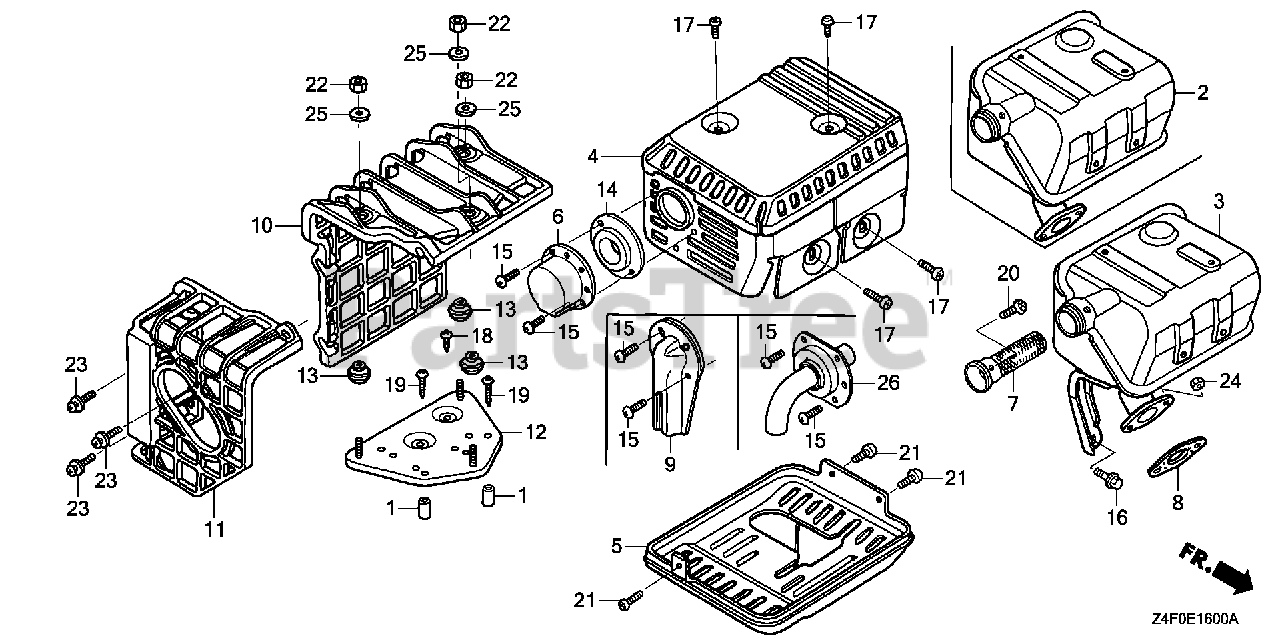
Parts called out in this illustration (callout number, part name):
1	COLLAR, AIR CLEANER HOUSING
2	MUFFLER (STD)
2	MUFFLER (ARRESTER)
4	PROTECTOR, MUFFLER (STD) (BLACK)
7	ARRESTER, SPARK
8	GASKET, MUFFLER
10	COVER, MUFFLER
11	COVER, RR. MUFFLER
12	BASE, MUFFLER COVER
13	SPACER, MUFFLER COVER
17	SCREW, TAPPING (5X8)
18	SCREW, TAPPING (5X8)
19	SCREW, TAPPING (5X25)
20	SCREW, TAPPING (4X6)
22	NUT, HEX. (5MM)
23	SCREW-WASHER (6X20)
24	NUT, HEX. (8MM)
25	WASHER, PLAIN (5MM)
